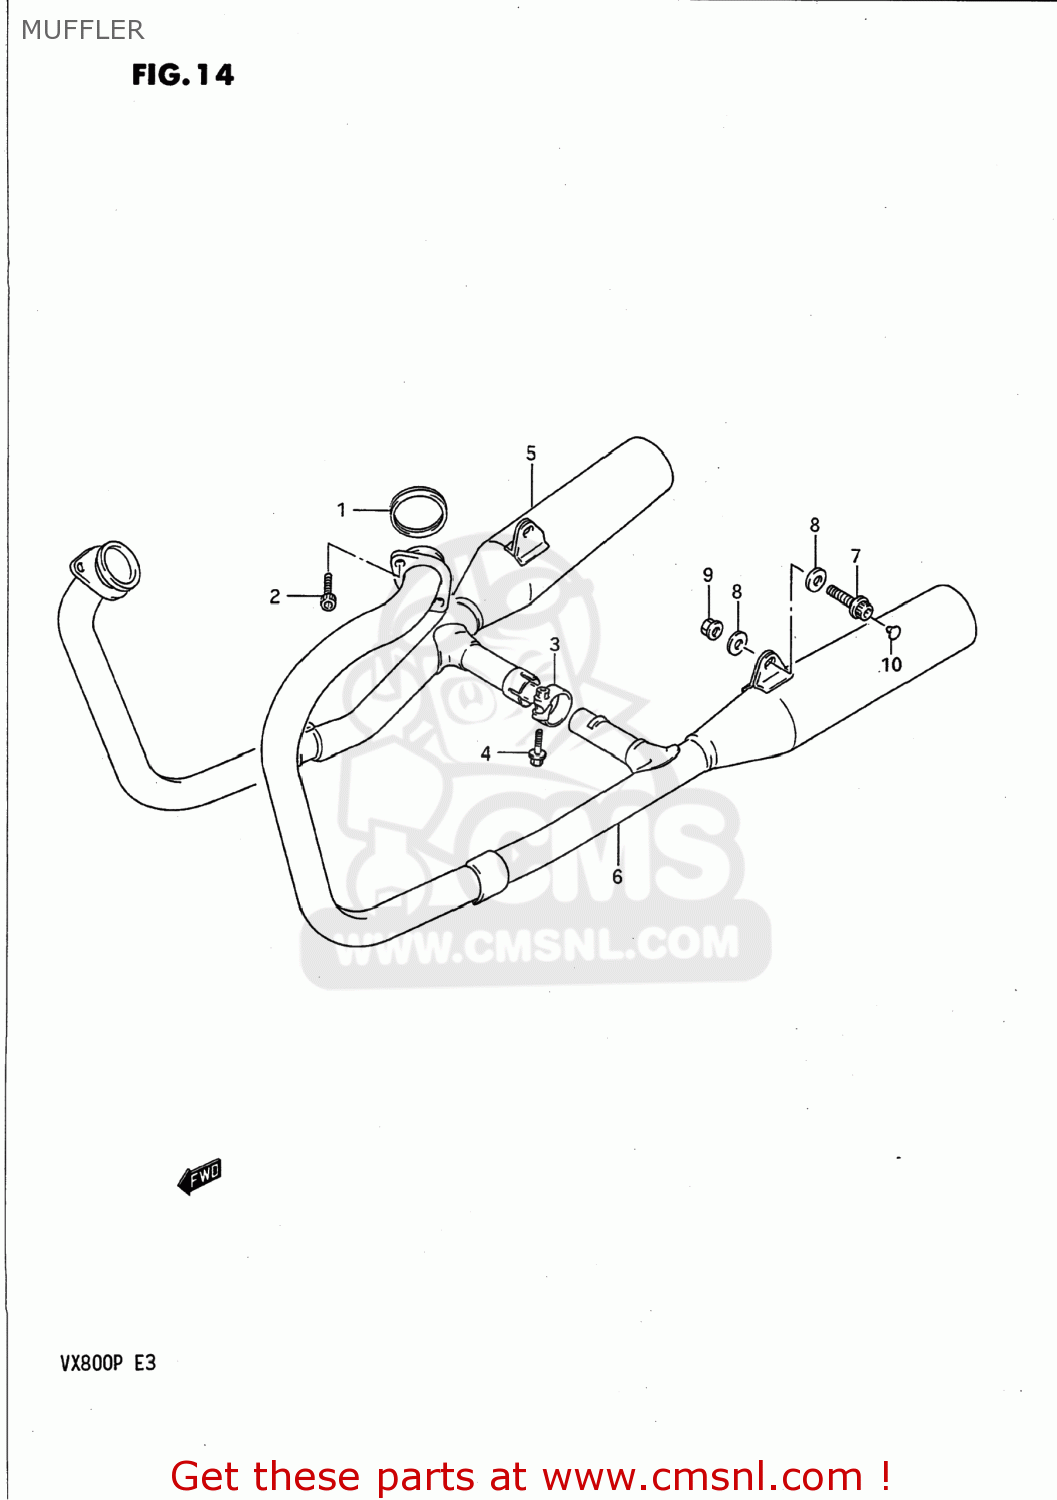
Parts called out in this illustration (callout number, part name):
1	GASKET,EXHAUST PIPE (NAS)
2	BOLT
3	CLAMP,MUFFLER JOINT
4	BOLT
5	MUFFLER ASSEMBLY
6	MUFFLER ASSEMBLY
7	BOLT
8	WASHER
9	NUT ,10MM
10	CAP(OD:12)
